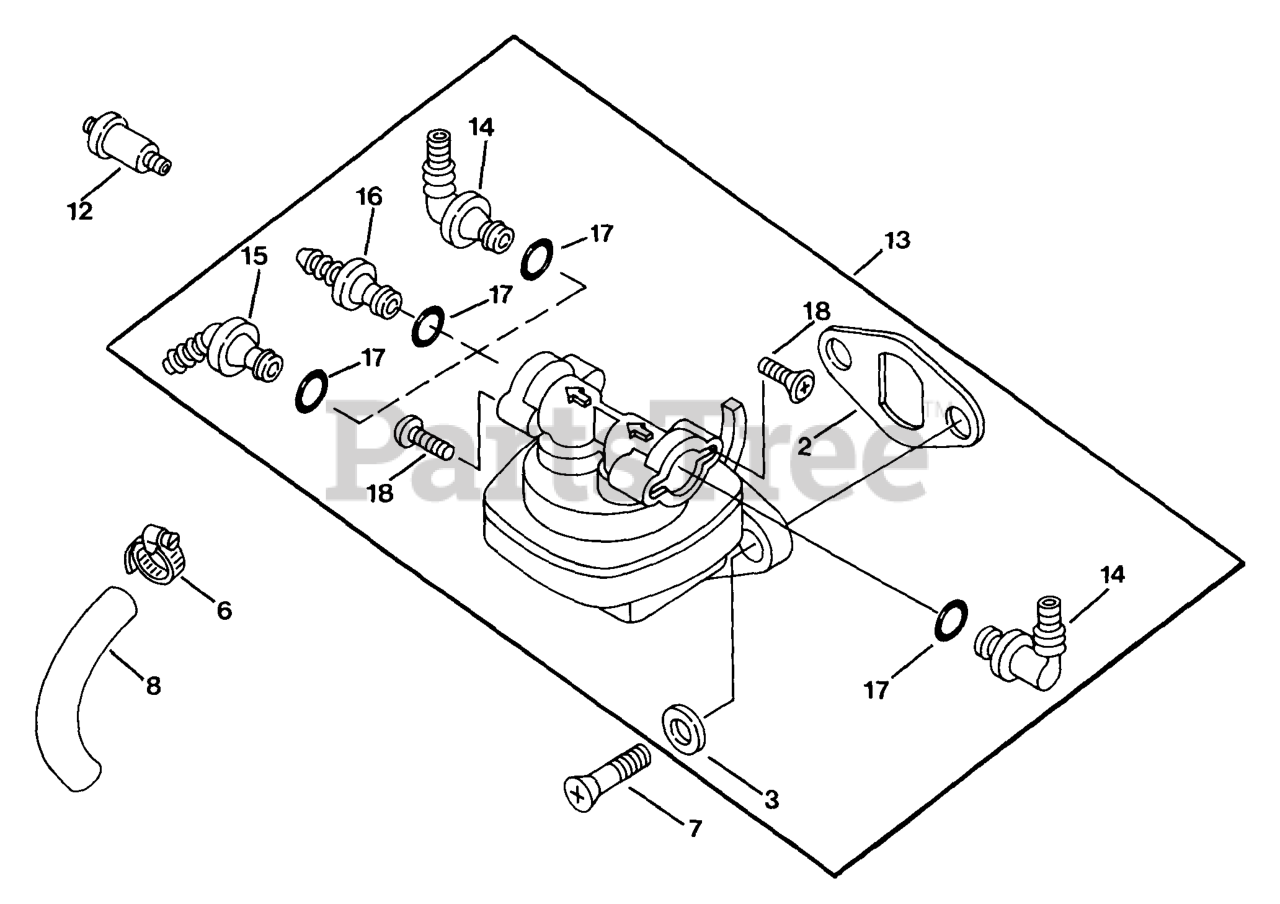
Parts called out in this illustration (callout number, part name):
2	GASKET - USE 25 041 09
3	WASHER, FLAT 1/4" (O.D. 1/2")
6	CLAMP, HOSE 1/2" USE 25 237 14-S
8	LINE - DISCONTINUED
13	PUMP - USE 47 559 04-S
14	CONNECTOR, 90 DEG. W/O-RING-DISC.
15	CONNECTOR, 45 DEG. W/O-RING-DISC.
17	O RING FITTING - DISCONTINUED
18	SCREW, LBD SCKT PAN - DISC.
